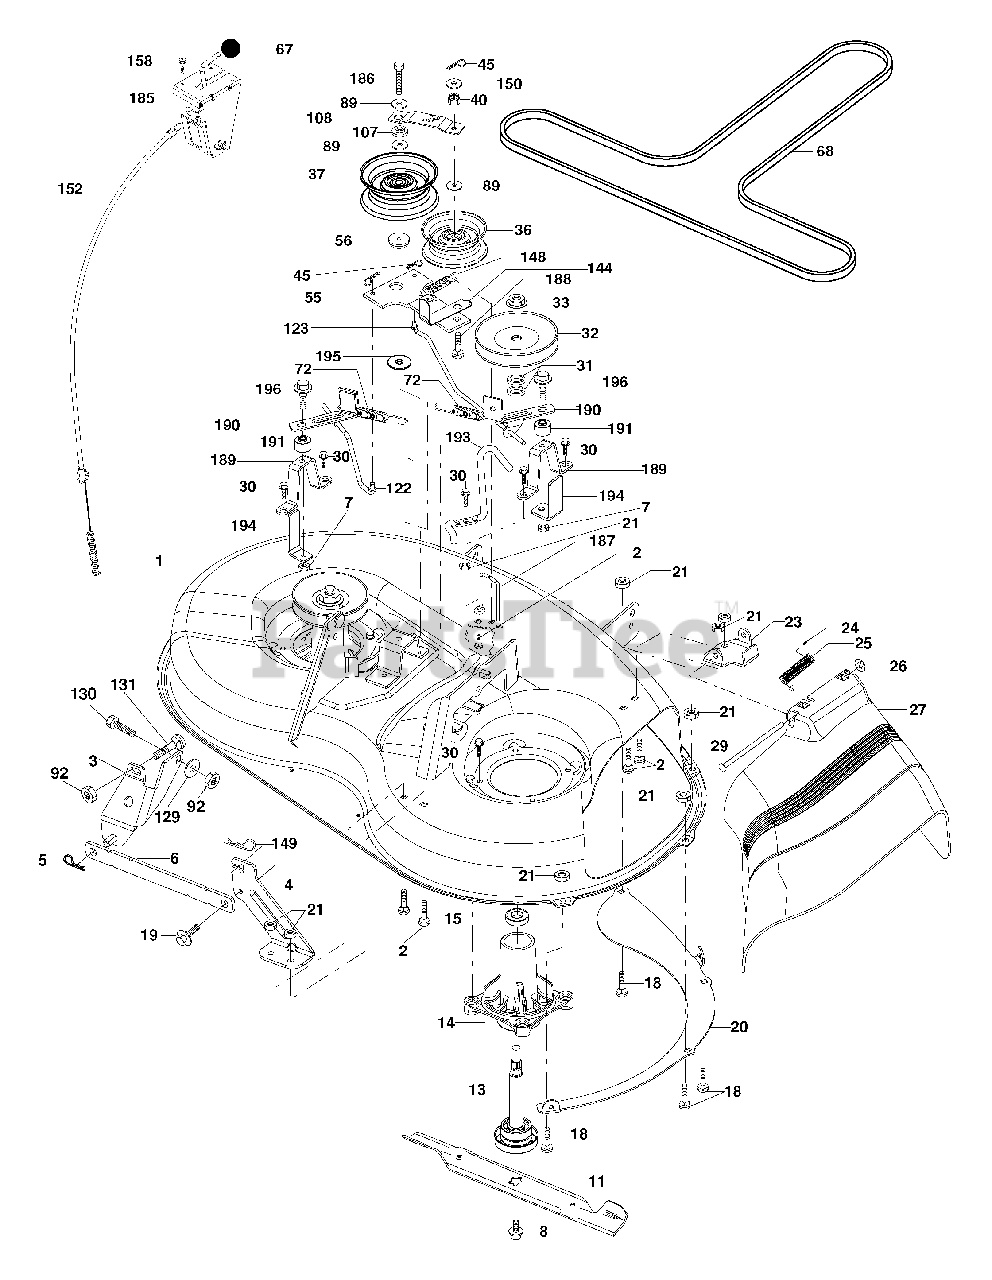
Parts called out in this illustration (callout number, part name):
1	Mower Housing Assembly
2	Bolt Carriage 5/16-18 x 3/4
3	Bracket Asm Fr. Sway Bar
4	Bracket Deck Sway Bar 38"/42"
5	Retainer Spring
6	Bar Sway Deck
7	Nut Lock Hex w/Insert 5/16-18 unc
8	Bolt 3/8-24 x 1.25 Gr. 8
11	Blade Mower
13	Shaft Assembly, Mandrel, Vented
14	Housing, Mandrel, Vented
15	Bearing, Ball, Mandrel
18	Blade Rdhd Sqnk 5/16-18 x 5/8
19	Bolt, Shoulder
20	Baffle Vortex Front
21	Nut
23	Bracket, Mower Deflector
24	Cap, Sleeve
25	Spring, Torsion, Deflector
26	Nut, Push
27	Shield, Deflector
29	Rod, Hinge
30	Screw Thdrol.
31	Washer, Spacer
32	Pulley, Mandrel
33	Nut, Toplock
36	Pulley, Idler, Flat
37	Pulley, Idler Flat
40	Nut, Crownlock 3/8-16 unc
45	Retainer
55	Idler Arm Assembly
56	Spacer, Retainer
67	Knob
68	V-Belt
72	Spring Brake Return
89	Washer 13/32 x 13/16 x 11 Ga.
92	Nut Lock 3/8-16
107	Spacer Retainer
108	Stiffener, Idler Arm
122	Rod, Brake LH
123	Rod, Brake RH
129	Washer 3/8
130	Bolt Hex 3/8-16 x 1 Gr. 5
131	Bolt Carr 3/8-16 x 1
144	Keeper Belt Idler Tension
148	Spring Return Idler
149	Retainer Spring Yellow
150	Washer 9/32 x 3/4 x 10 Ga.
152	Clutch Cable 38"
158	Screw Hex Thd Cut 1/4-20 x 1/2
185	Head Asm Cable Clutch
186	Screw Hex Wsh Thdrol 3/8-16 x 2-3/4
187	Keeper Belt M Shape
188	Bolt Carriage Idler
189	Brake Stand
190	Brake Arm
191	Brake Spacer
193	Keeper Belt Rh Mandrel
194	Brake Guard
195	Washer 13/32 x 2 x 10 Ga.
196	Bolt/Washer Asm. 5/16-18
